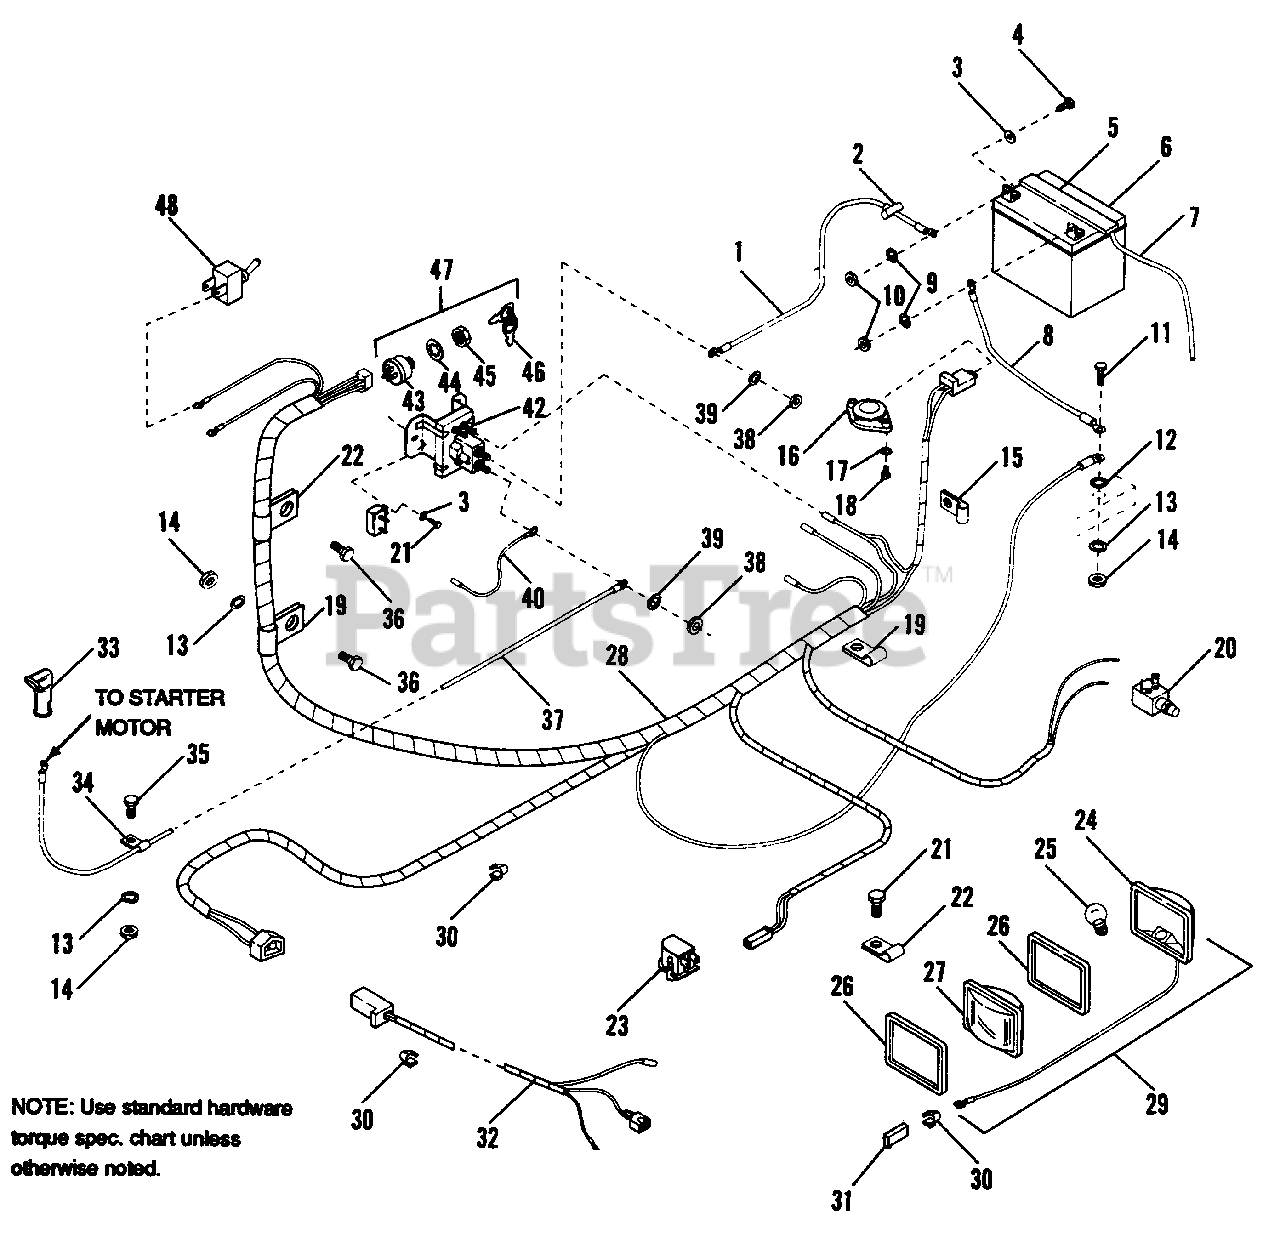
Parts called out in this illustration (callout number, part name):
1	WIRE ASSY., Battery to Solenoid
2	BOOT, Insulator
3	WASHER, Plain
4	CAPSCREW, Hex 1/4-20 x 3/4
5	VENTCAP, Battery
7	HOSE, Drain, Battery
8	WIRE ASSY., Battery to Engine Ground (1681842)
8	WIRE ASSY., Battery to Engine Ground (1691844, 1691846)
9	LOCKWASHER, Spring 1/4
10	NUT, Hex 1/4-20
11	CAPSCREW, Hex Head 5/16-18 x 2 G5
12	LOCKWASHER, External Tooth 5/16
13	LOCKWASHER, Spring 5/16 (1691844, 1691846) LOCKWASHER, Spring 5/16 (1691842)
14	NUT, Hex 5/16-18
16	SWITCH ASSY., Safety, Seat
17	LOCKWASHER, External Tooth 1/4
18	SCREW, Round Head 1/4-20 x 3/4
20	SWITCH, Interlock, PTO
21	SCREW, Taptite 1/4-20 x 5/8
22	CLAMP, Wire
23	SWITCH, Interlock (Pedal Start)
24	REFLECTOR ASSY.
27	LENS, Clear Plastic
28	HARNESS ASSY., Wheel Steer
29	HEADLIGHT ASSY. (Incl. Ref. Nos. 24-28)
30	CLIP (1691844, 1691846) CLIP (1691842)
31	CONNECTOR BODY
32	WIRING ASSY., Harness to Engine (1691842)
34	CLAMP, Wire (1691842)
35	CAPSCREW, Hex 5/16-18 x 3/4 (1691842)
36	CAPSCREW, Hex 5/16-18 x 1
37	WIRE ASSY., Solenoid to Starter (1691842)
37	WIRE ASSY., Solenoid to Starter (1691844, 1691846)
38	NUT, Hex 5/16-24
39	LOCKWASHER, Spring 5/16
40	WIRE, Circuit Breaker to Solenoid
41	CIRCUIT BREAKER
42	SOLENOID
43	SWITCH, Ignition (See Ref. No. 47)
44	LOCKWASHER, Internal Tooth 5/8
45	NUT, Hex 5/8-32
46	KEYS & RING
47	IGNITION SWITCH ASSY. (Incl. Ref. Nos. 43-46)
48	SWITCH ASSY., Headlight
